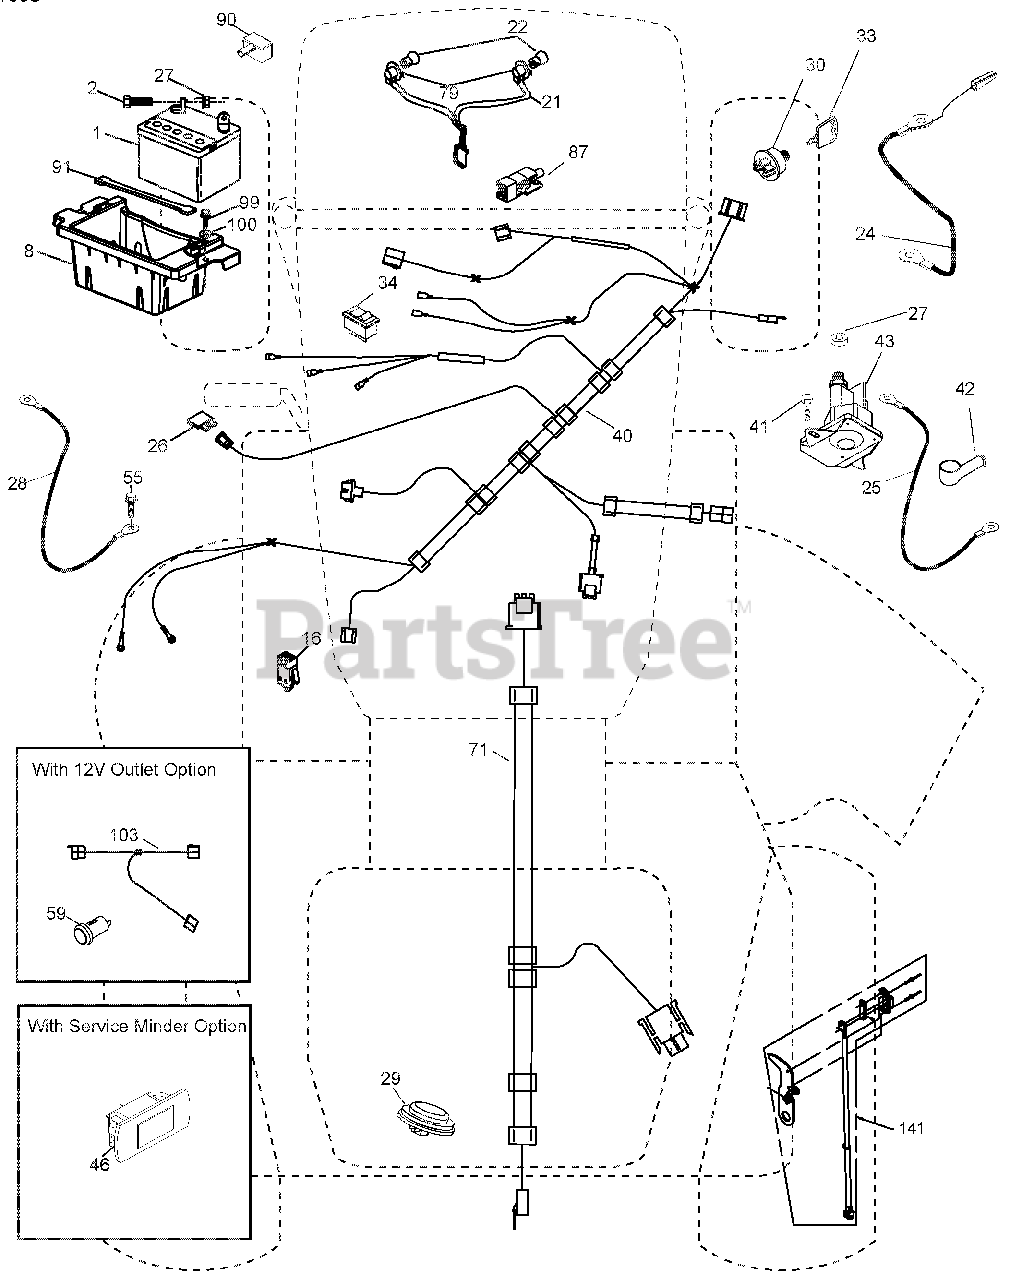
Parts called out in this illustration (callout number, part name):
1	BATTERY.12.VOLT.28.AMP.WET
2	BOLT.HEX.HD.1/4-20UNC X 3/4
8	BOX.BATTERY.MOUNT.FRONT.LT
16	SWITCH.INTERLOCK.NONO.GRAY
21	HARNESS ASM.LIGHT.22"(4152J)
22	BULB.LIGHT.#1156
24	CABLE.BTRY.PSWRE.DSH SOL.8"TEX
25	CABLE.STARTER.6GA.BL/RED.14.5"
26	FUSE.20 AMP.
27	Nut, Keps Hex 1/4-20 unc
28	CABLE.GROUND.21"BLK.6 GA.90T
29	SWITCH.SEAT.DELTA.OPC.9LB.
30	SWITCH.IGN.DLTA.P-IN.ROS
33	KEY/CHAIN.BLISTER PACK.GEN.CE
34	SWITCH.LIGHT/RESET.B/B/RED.
40	HARNESS.IGN.DASH.CBL.YTGT.PRED
41	Screw 1/4-20 x 1/2
42	COVER.TERMINAL.RED
43	SOLENOID.W/BRASS PLUNGER.2005
55	SCREW.5/16-18X3/4.SMGML.TAP/R
71	HARNESS.IGN.CHASSIS.TEX
79	SOCKET ASM.BULB.TWISTLOCK
87	SWITCH.INTRLCK.CLUTCH.CABLE.TX
90	COVER.TERMINAL.BATTERY.FR.TEX
91	STRAP.BATTERY.MOUNT.FRONT
99	SCREW.HEXWSH.THDROL.1/4-20X3/4
100	WASHER.9/32 X 7/8 X 16GA.
141	KIT.T2.ROS.(71677)
